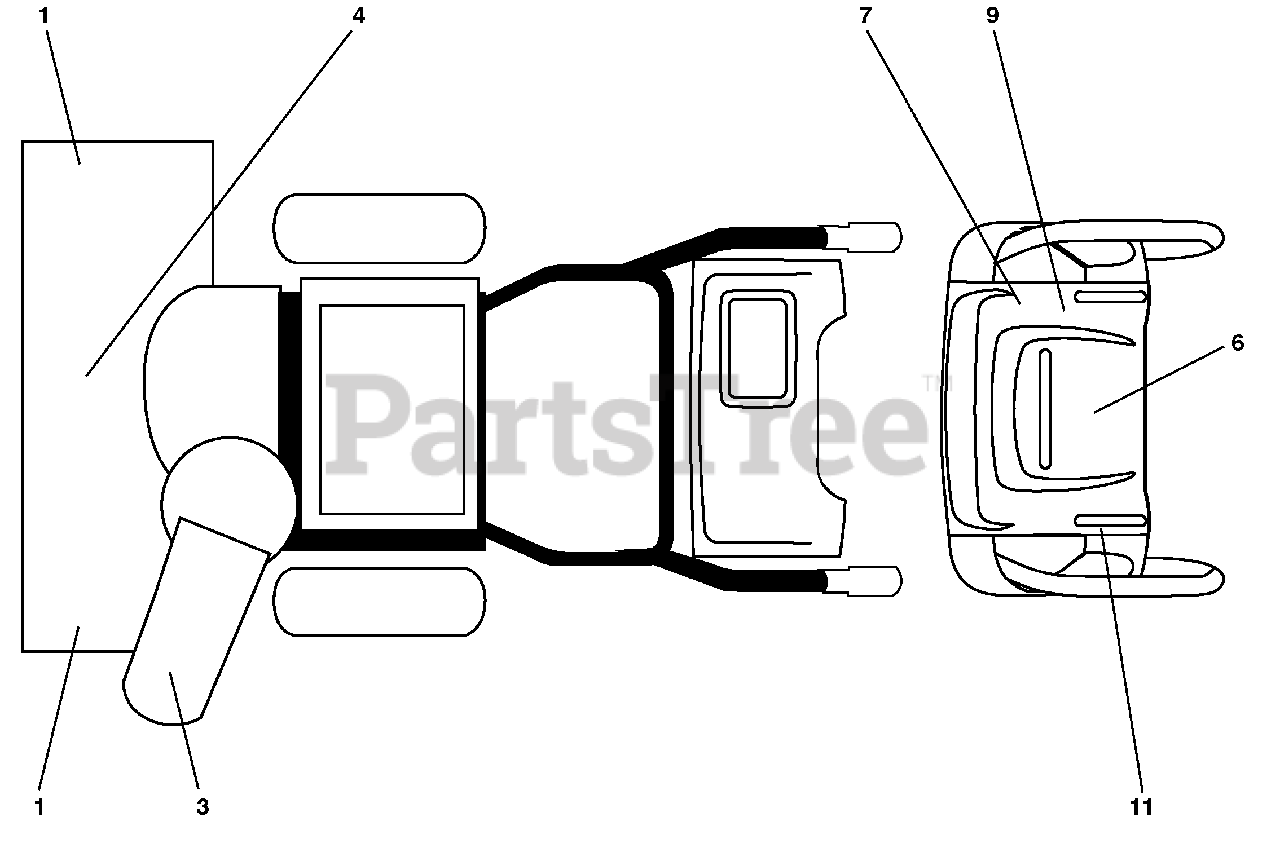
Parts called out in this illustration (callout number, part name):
1	DECAL, DANGER
3	DECAL, DANGER, DEFLECTOR
4	DECAL, DANGER
6	DECAL, INSTRUCTION
7	DECAL, AUGER LEVER RT
9	DECAL, SPEED CONTROL
11	DECAL, TRACT/CLUTCH LEVER
